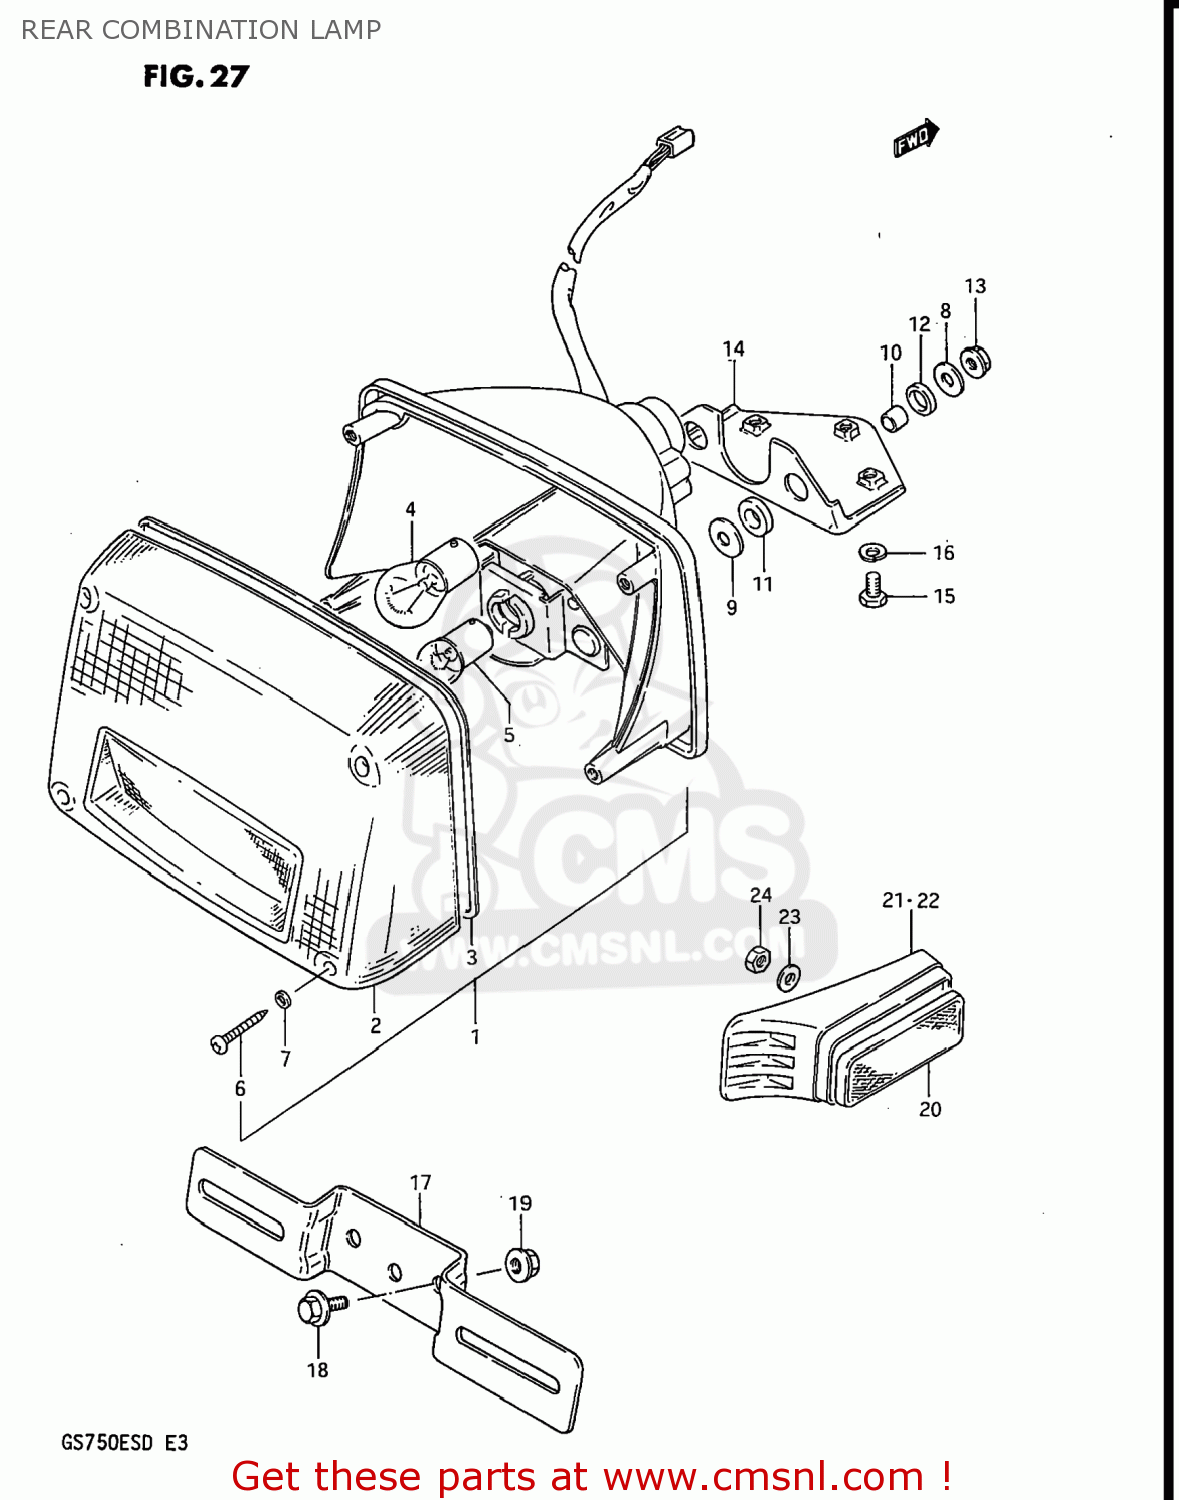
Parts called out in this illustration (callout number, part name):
1	LAMP ASSEMBLY,REAR COMBINATION
2	LENS
3	GASKET (NAS)
4	BULB(12V23W)
5	BULB
6	SCREW,REAR COMBINATION LAMP
7	GASKET (NAS)
8	WASHER
9	WASHER(6,5X22X1.6)
10	SPACER(6.1X9X7.5)
11	CUSHION
12	CUSHION
13	NUT 6MM
14	BRACKET,REAR COMBINATION LAMP
15	BOLT
16	LOCK WASHER
17	PLATE,REAR LICENSE
18	BOLT
19	NUT 6MM
20	REFLECTOR,REFLEX
21	SPACER,REAR REFLECTOR,RIGHT
22	SPACER
23	WASHER(5.2X16X1)
24	NUT
